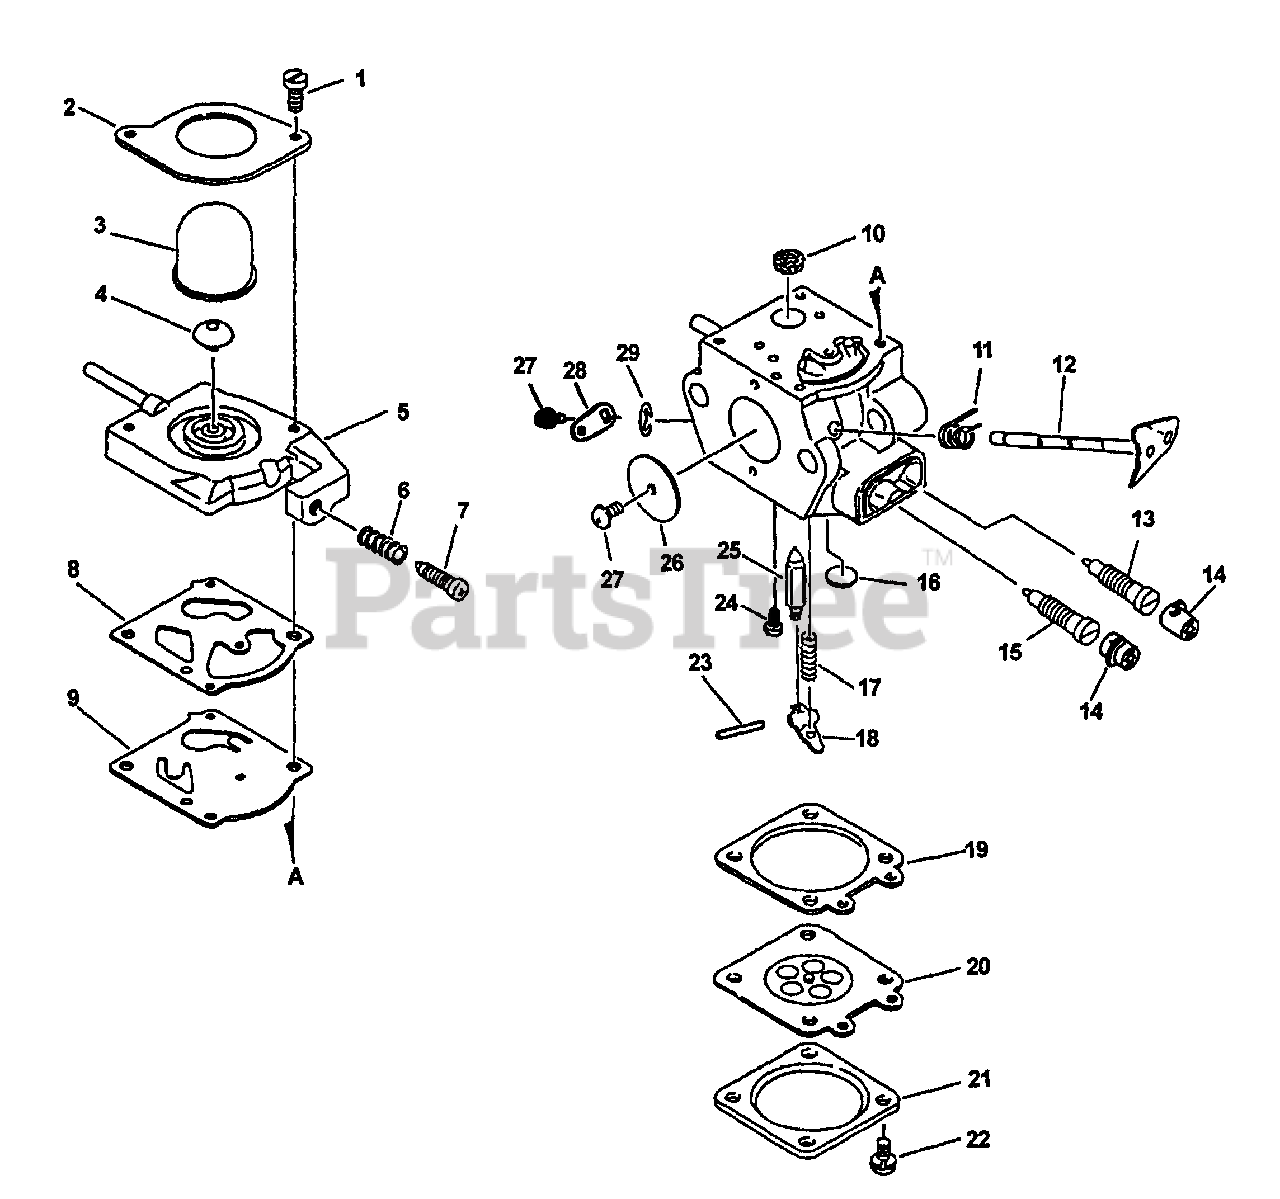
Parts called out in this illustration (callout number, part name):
2	RETAINER, PURGE BULB
3	BULB, PURGE
4	VALVE, CHECK
5	COVER, FUEL PUMP
6	SPRING, IDLE ADJUST
7	SCREW, IDLE ADJUST
10	STRAINER
11	SPRING, THROTTLE RETURN
12	SHAFT ASSY, THROTTLE
13	NEEDLE, HIGH SPEED
14	CAP, LIMITER
15	NEEDLE, IDLE
16	PLUG, WELCH
17	SPRING, METERING LEVER
18	LEVER, METERING
19	GASKET, METERING
20	DIAPHRAGM, METERING
21	COVER, METERING DIAPHRAGM
23	PIN, METERING LEVER
24	SCREW, METERING LEVER PIN
25	VALVE, INLET NEEDLE
26	VALVE, THROTTLE
28	LEVER, THROTTLE
